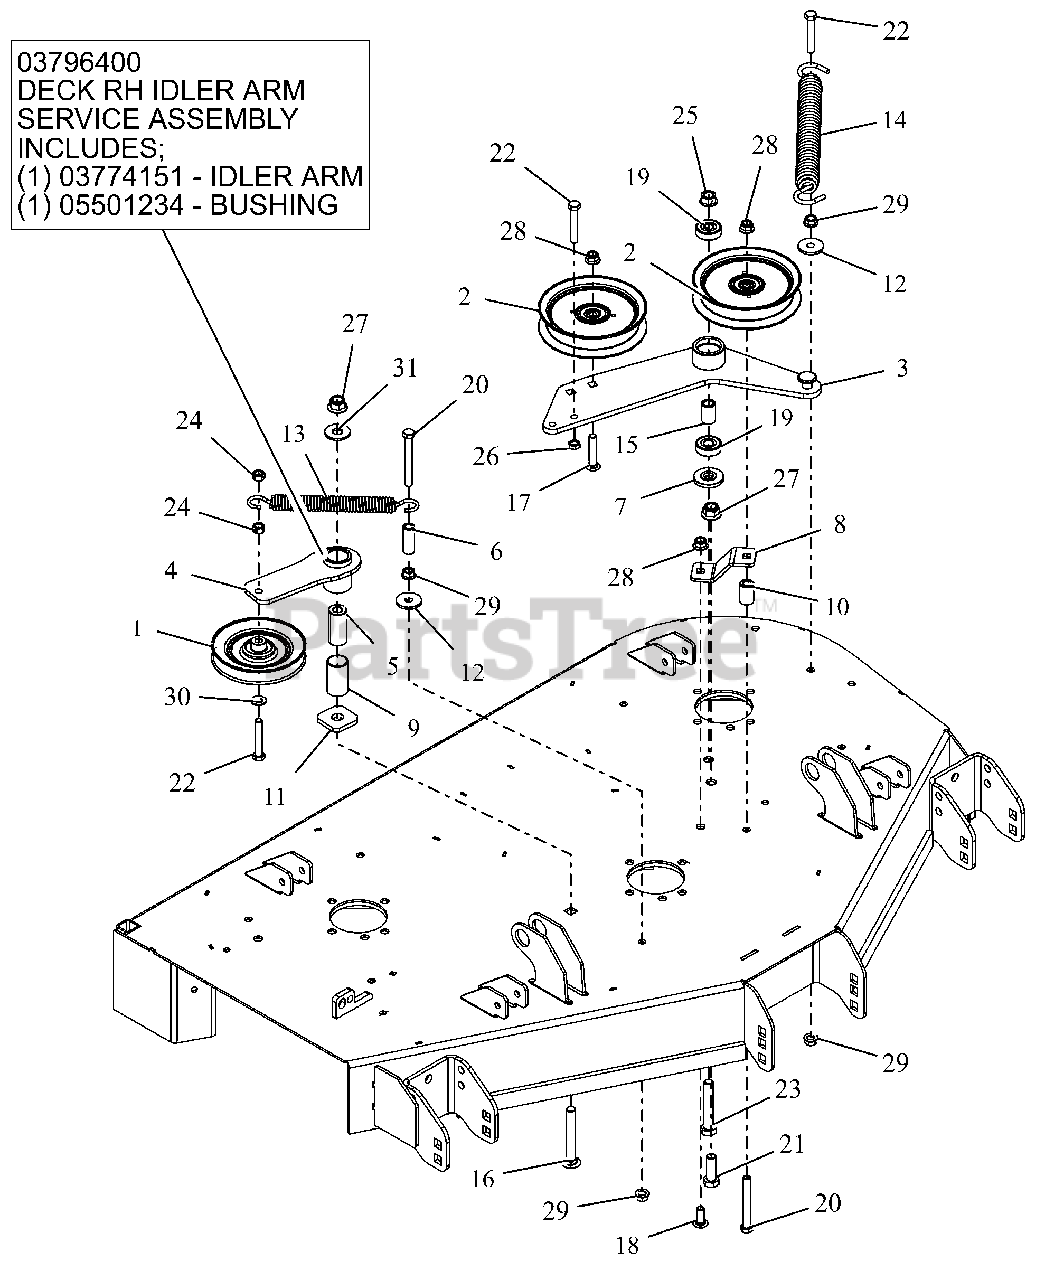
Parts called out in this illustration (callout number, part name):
1	IDLER, V-5.00"
2	IDLER, FLAT 5.00"
3	DECK PTO IDLER ARM WLDMT - BLK
4	WMT, IDLER ARM - BLACK
4	ASM, IDLER ARM (DECK)
4	BSHG, 1.00X1.125X1.937
5	BSHG, SPCR .502X.997X2.03 PM
6	SPACER, .375IDX.625ODX1.66 PM
7	SPACER, IDLER ARM
8	PTO FIXED IDLER MTG BRKT -RED
9	BSHG, 1.00X1.125X1.937
10	BUSHING, SLV .380X.750X1.190
11	WSHR-FLT .640X1.75X.250
12	WSHR-FL-STL .406X1.375X.135 YZ
13	SPRING, EXTENSION
14	SPRING, EXTENSION
15	SPACER .510 X .75 X 1.1485
16	@BLT-RDHDSQNK .50-13X3.50 G5YZ
17	BLT-RDHDSQNK .38-16X2.00 SHTYW
18	@BLT-RDHDSHSQNK.38-16X1.0 G5YZ
19	BRG-BALL .500X1.38X.437
20	@BLT-HEX .38-16X3.25 GR5 YWZC
21	@BLT-HEX .50-13X1.50 GR5 YWZC
22	@BLT-HEX .38-16X2.25 GR5 YWZC
23	@BLT-HEX .50-13X3.00 GR5 YWZC
24	@NUT-LK-CTR .38-16 YWZC
25	NUT-LK-CTR-FLG .50-13 YWZC
26	NUT-HEX-JAM .375-16 YWZC
27	@NUT-LK-NYL-FLG .50-13 YWZC
28	@NUT-LK-NYL-FLG .38-16 YWZC
29	@NUT-SPNLK-FLG .375-16 YWZC
30	@WSHR-FL-STL.406X.812X.065 YWZ
31	@WSHR-FL-STL.563X1.38X.109YWZC
